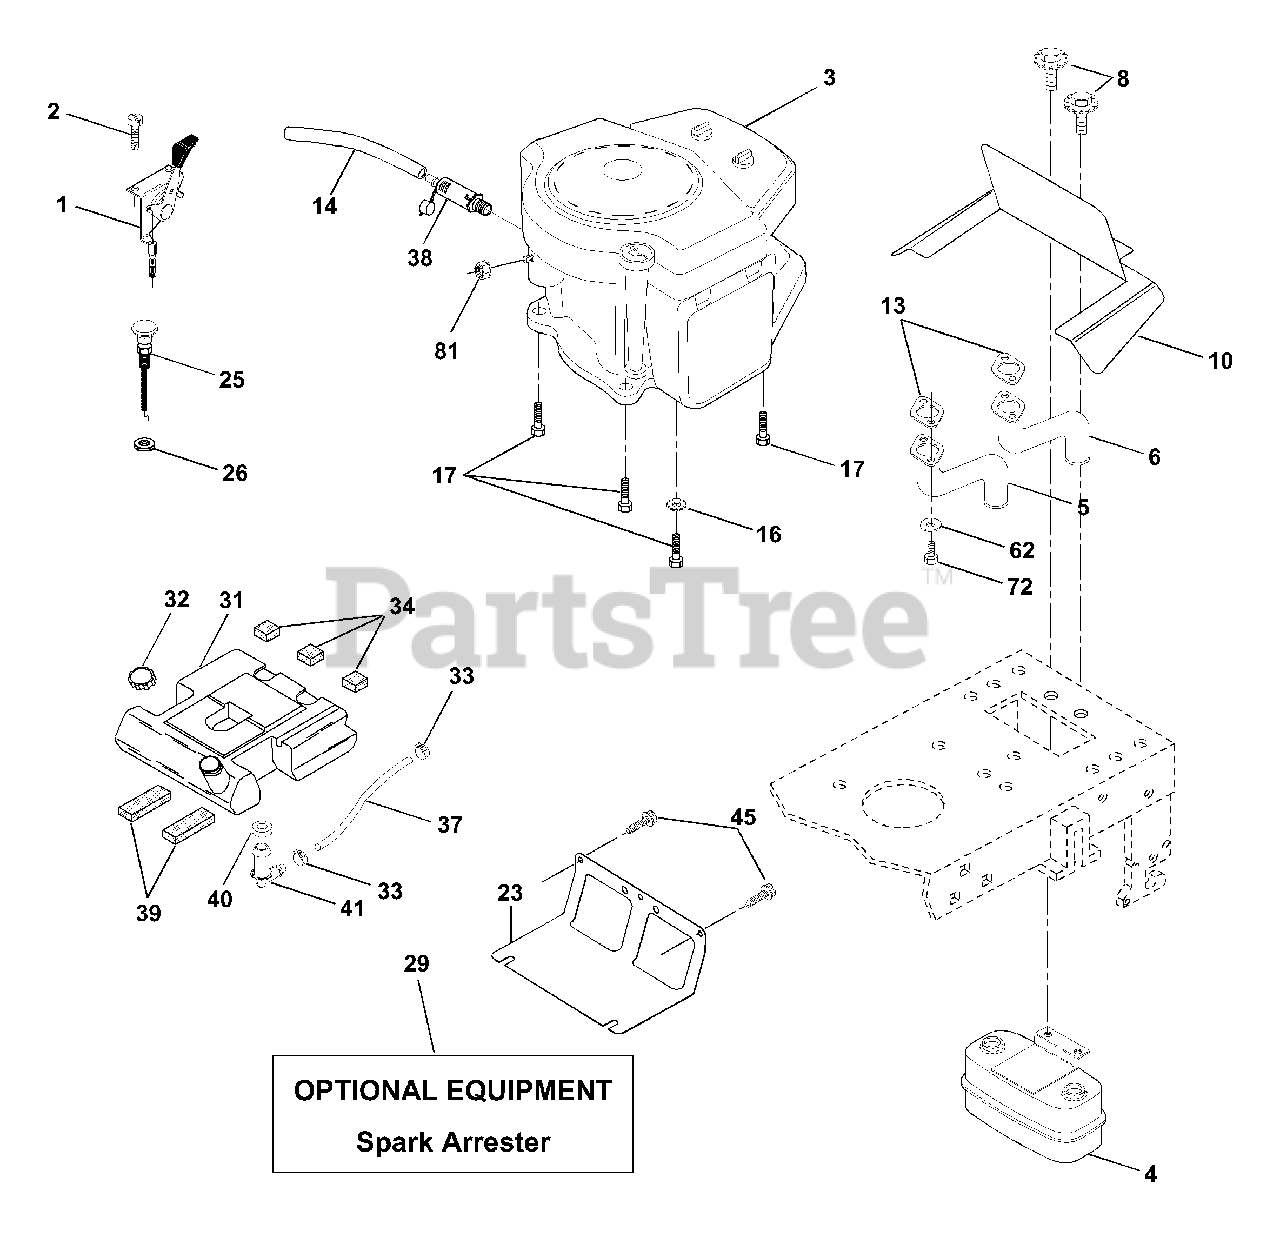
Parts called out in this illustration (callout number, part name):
1	Control Throt Flg 180 LH
2	Screw Hex Thd Cut 1/4-20x5/8 T
3	Engine B&S
4	Muffler Asm Twin Lo-Tone
5	Exhaust Tube LH
6	Exhaust Tube RH
8	Bolt 5/16-18unc x 3/4 W/Sems
10	Shield Browning B&S Intek II
13	Gasket Muffler
14	Tube Drain Oil Easy
16	Washer Lock Ext Tooth 3/8
17	Screw Thdrol 3/8-16 x 1-1/2
23	Shield Browning
25	Choke Control 37"
26	Nut, Keps 3/8-24 Unf
29	Kit Spark Arrestor (Flat Scrn)
31	Tank Fuel 3 50 Rear
32	Cap Asm Fuel Top N/Lany Vented
33	Clamp Hose Blk
34	Pad, Spacer
37	Line Fuel
38	Plug Drain Oil Easy
39	Pad, Idler
40	Bushing
41	Stem Tank Fuel
45	Screw Hexwsh Thdr 3/8-16 x 3/4
62	Washer Lock Hvy Hlcl Spr 5/16
72	Screw Hex Hd Cap 5/16-18 x 3/4
81	Nut Keps Hex 1/4-20 Unc
